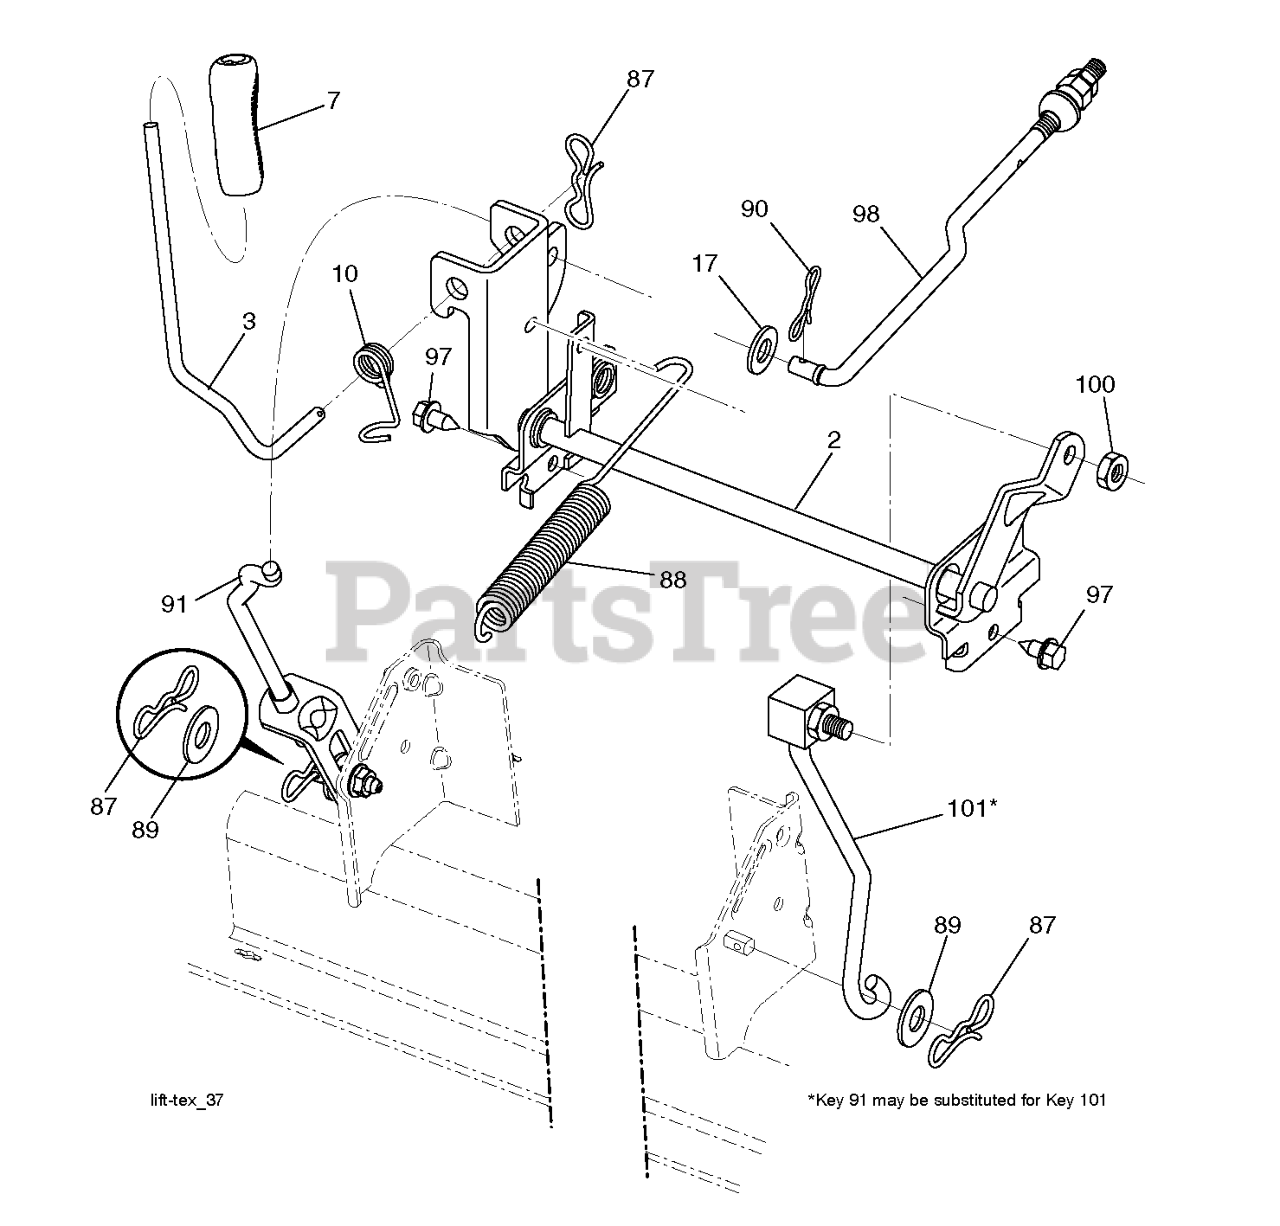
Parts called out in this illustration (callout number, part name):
2	SHAFT.ASM.CROSS.LIFT
3	LEVER.LIFT.HANDLE.LT
7	GRIP.HANDLE.LIFT.PVC.BLACK
10	SPRING.TORSION.LIFT.HANDLE
17	Washer 13/32 x 13/16 x 12 Gauge (AYP part number)
87	PIN.COTTER.7/16.BOW TI.
88	SPRING.LIFT.ASSIST
89	WASHER.CLEAR.ZINC
90	PIN.COTTER.5/16.BOW TI
91	LINK.LIFT.ASM.REAR.GT.
97	SCREW, 3/8-16X3/4
98	LINK.FRONT.MOWER.SUSP.ASM.BLK
100	Nut, Hex, Centerlock 3/8-16 UNC (AYP part number)
101	LINK.ASSY.BLACK.431
